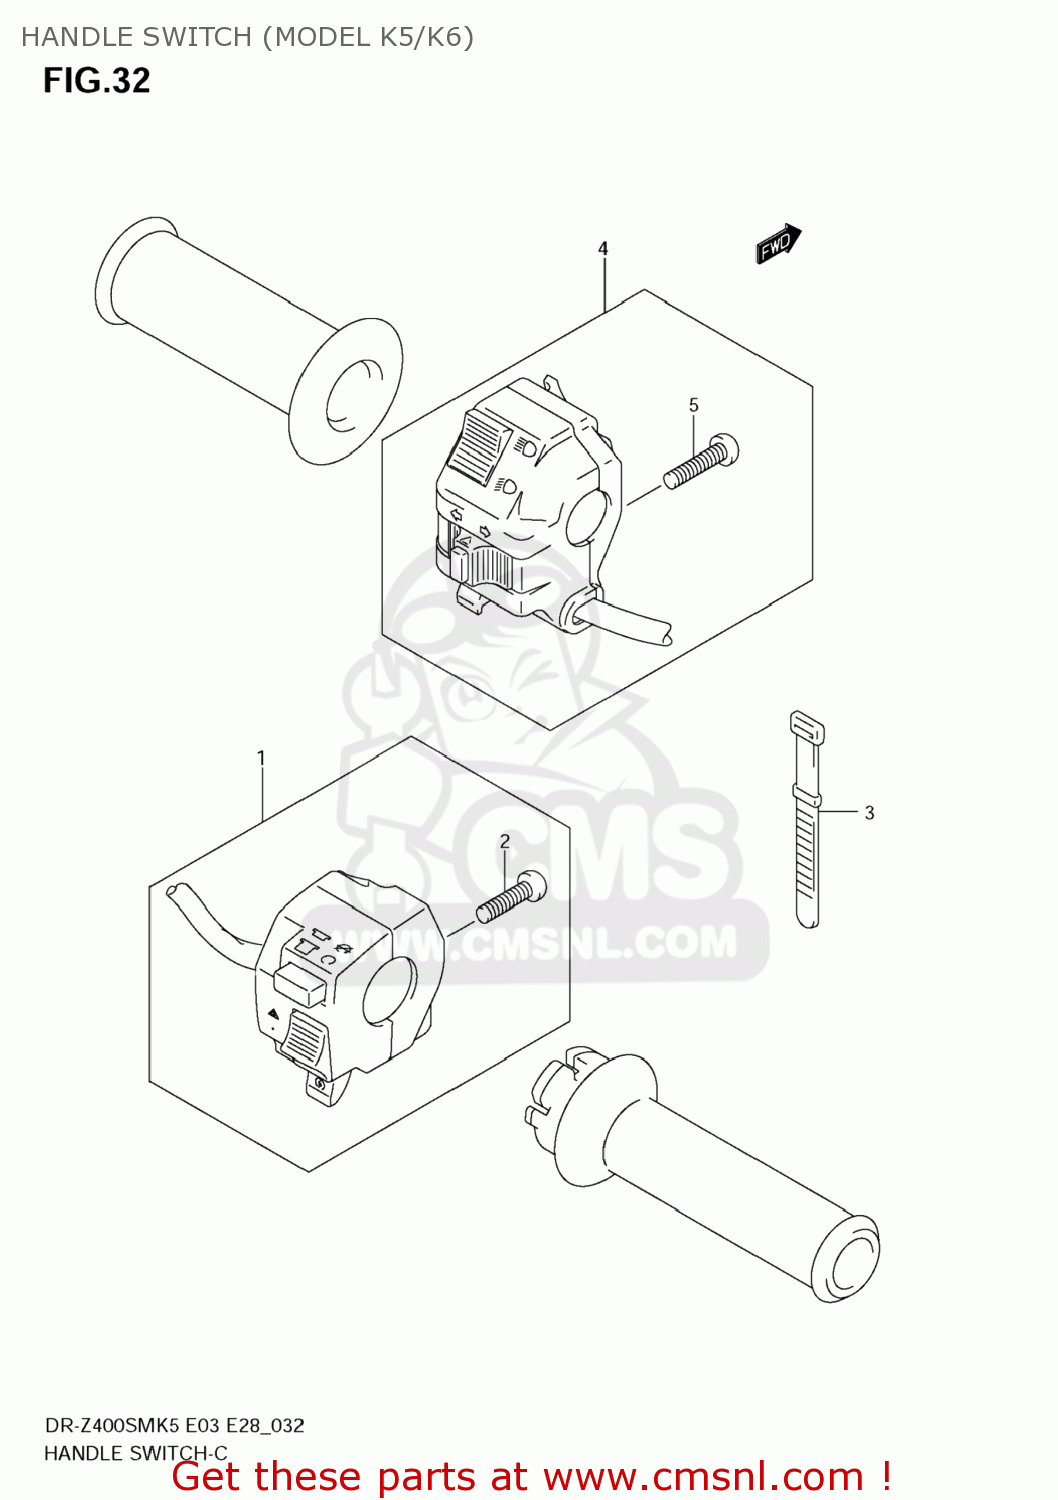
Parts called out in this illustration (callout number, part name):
1	SWITCH ASSY,HANDLE,R
2	SCREW
3	CLAMP(L:120)
4	SWITCH ASSY,HANDLE,L
5	SCREW
